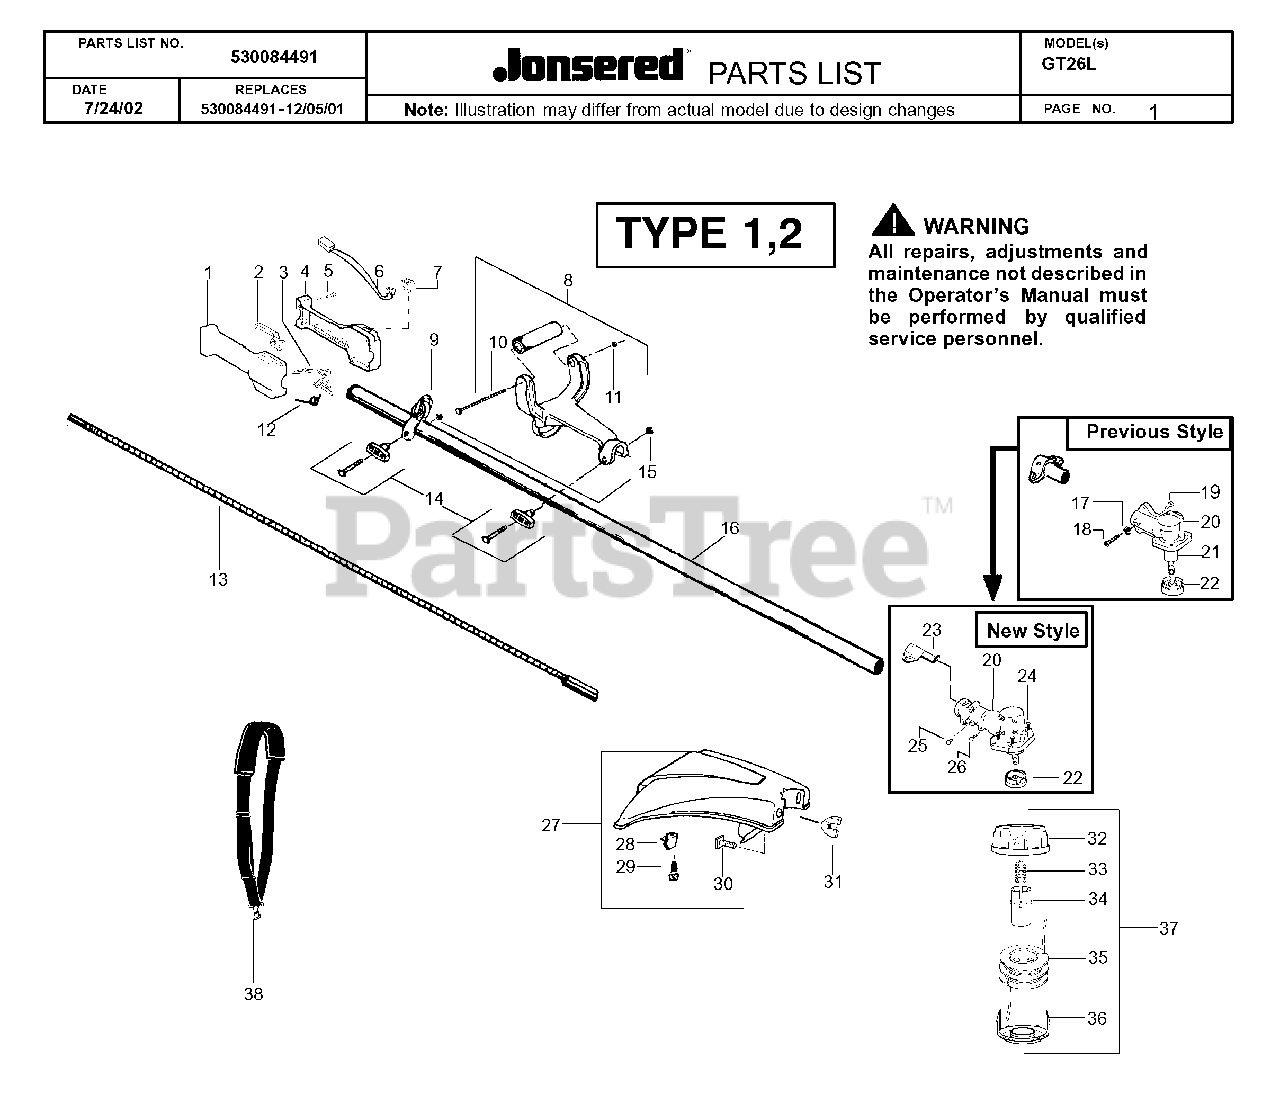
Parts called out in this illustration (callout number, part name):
3	THROTTLE TRIGGER
5	SCREW-10-14 X 13/16 (PL
8	ASS'Y-HANDLE ANTIVIB
9	ASSY-CLAMP HARNESS
10	SCREW-12-24 X 4-11/16 P
11	NUT-12-24 (HEX)
14	KIT "T" HANDLE
17	LOCKWASHER-LOCATOR-TYPE 2
18	SCREW-PINCH CLAMP-TYPE 2
19	SCREW - LOCATOR - TYPE 2
23	BRACKET,SHIELD
24	SCR 10-24 MS LDK PAN PH
26	SCREW
27	SHIELD KIT ASS'Y, TYPE 2
28	LINE LIMITER, TYPE 2 NLA
29	SCREW-10-16 X 1/2, TYPE 2
30	BOLT, TYPE 2
31	WINGNUT, TYPE 2
35	SPOOL W/LINE
37	CUTTING HEAD
38	STRAP SHOULDER
530031159	HEX WRENCH 5/32
